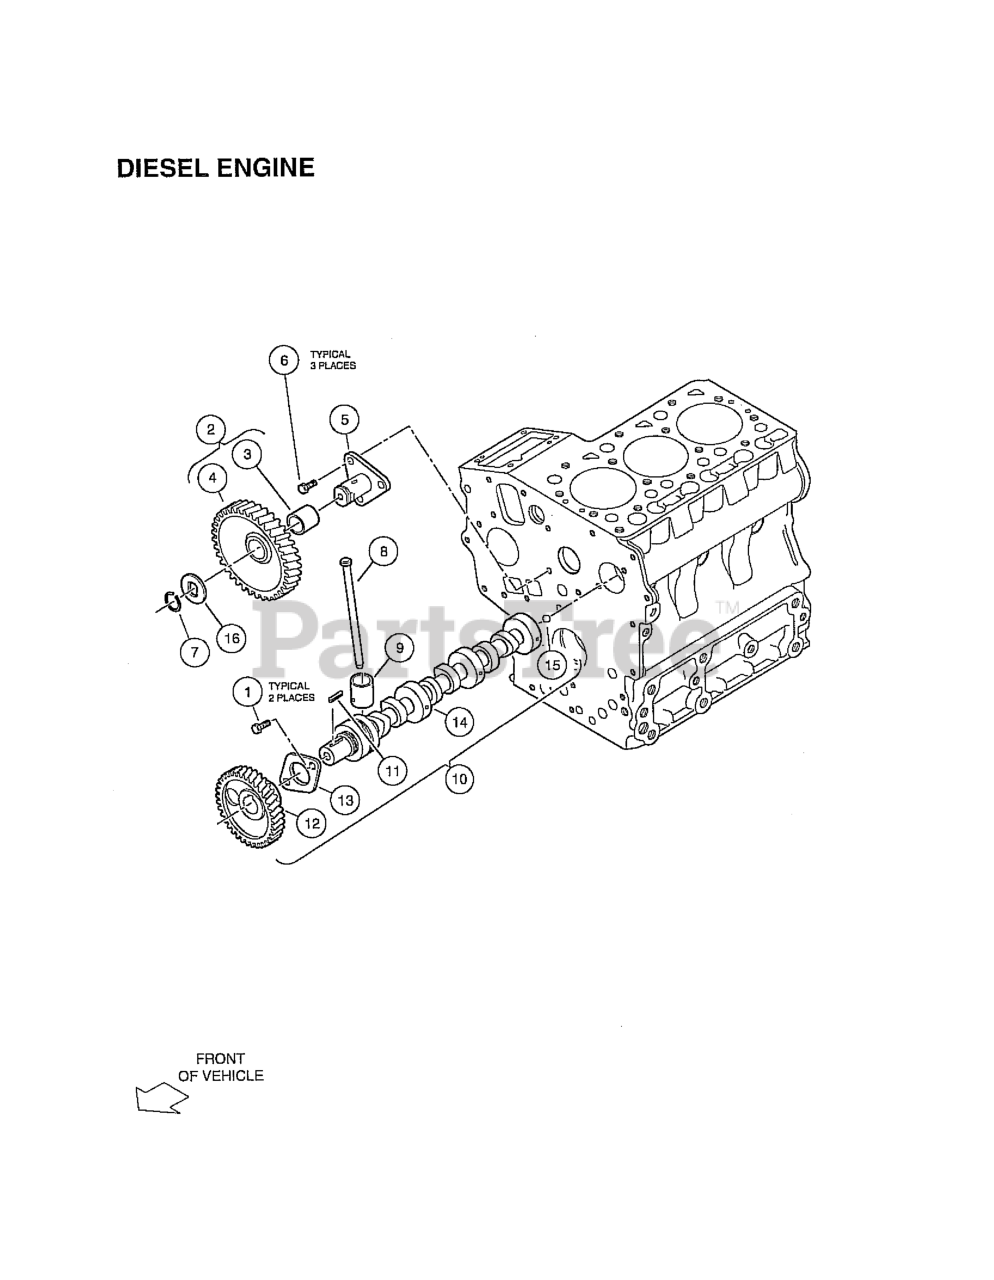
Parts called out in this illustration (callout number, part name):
1	BOLT, D722, CAM END
2	COMP, GEAR, IDLE
5	SHAFT, IDLE GEAR
6	BOLT, M6 X 1 X 14
7	RING, SNAP
10	ASSY CAMSHAFT, LONG
13	STOPPER, CAMSHAFT
15	BALL-CHECK
16	COLLAR, IDLE GEAR
